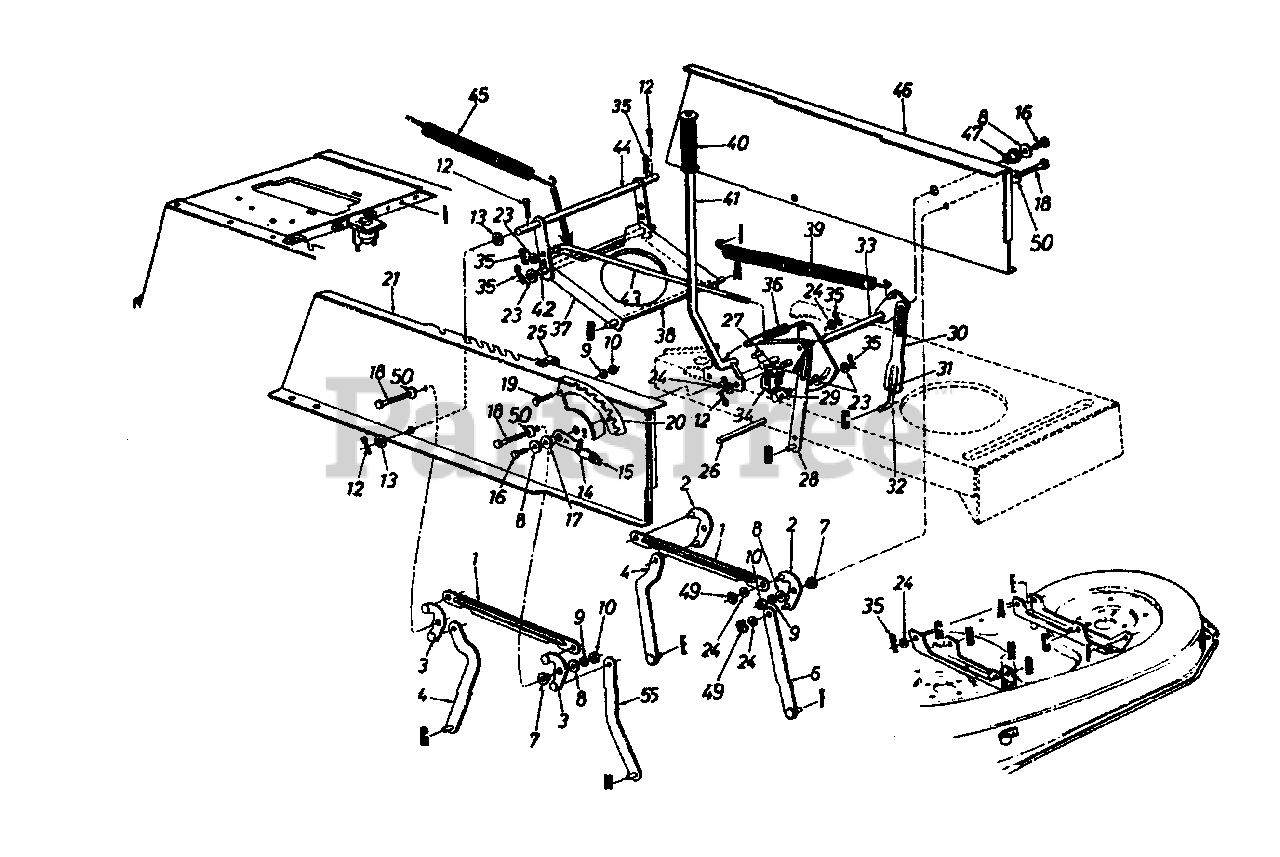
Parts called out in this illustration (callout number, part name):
3	Pivot Link Ass'y.-R.H.
7	Shld. Spacer .318" I.D.
8	Fl-Wash..344" I.D. x .62" O.D.
9	L-Wash. 5/16" I.D.
10	Hex Nut 5/16-18 Thd. (Gr. 5)
12	Cotter Pin 1/8" Dia.
13	Fl-Wash..635" I.D. x 1.0" O.D.
15	Knob
16	Hex Wash. TT-Tap Scr.5/16-18 x .75" Lg.
17	Flange Brg..63" I.D.
18	Hex Wash. Hd. Scr. 5/16-18x .875" Lg.
19	Hex Bolt 5/16-18 x .75" Lg.
20	Index Brkt.
24	Fl-Wash..531" I.D. x .93" O.D.
25	Clamp
26	Running Board Rod
27	Hex Wash. Hd. Tap Scr.
31	Hex Nut 1/2-20 Thd. (Gr. 5)
32	Lift Link Adjuster
35	Inter. Cotter Pin 3/8" Dia.
36	Extension Spring
39	Extension Spring
40	Grip (Lift Handle)
43	Disengagement Rod
49	"E"-Ring
50	Bell-Wash..325" I.D.
